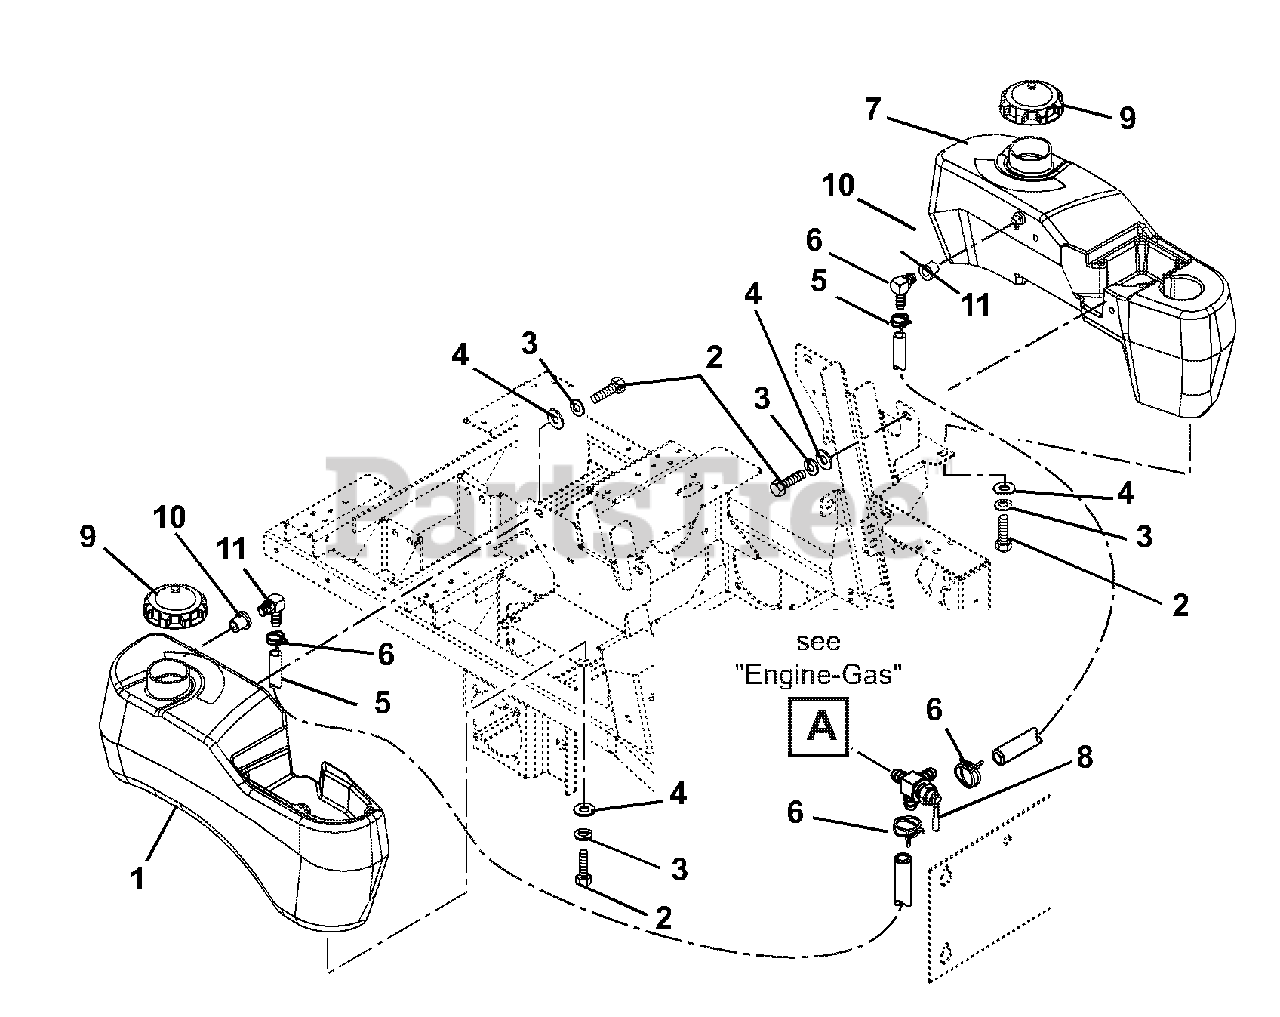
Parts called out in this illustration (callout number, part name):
1	Tank, Gas Fuel-Right Hand (058, 059, 073, 074)
2	Bolt, Hex .31-18 x .75 Grade 5
3	Washer, Locking .31 x .078
4	Washer, Flat Steel .38 x .875 x .083
5	Gas Line-Bulk .25 I.D. (058, 059, 073, 074)
6	Clamp, Hose Wire .49/.51 x .116 (058, 059, 073, 074)
7	Tank, Left Hand Fuel (EYE-Q) 200 Series (058, 059, 073, 074)
8	Valve, Fuel (058, 059, 073, 074)
9	Cap, Gas (058, 059, 073, 074)
11	Fitting, Tank (058, 059, 073, 074)
